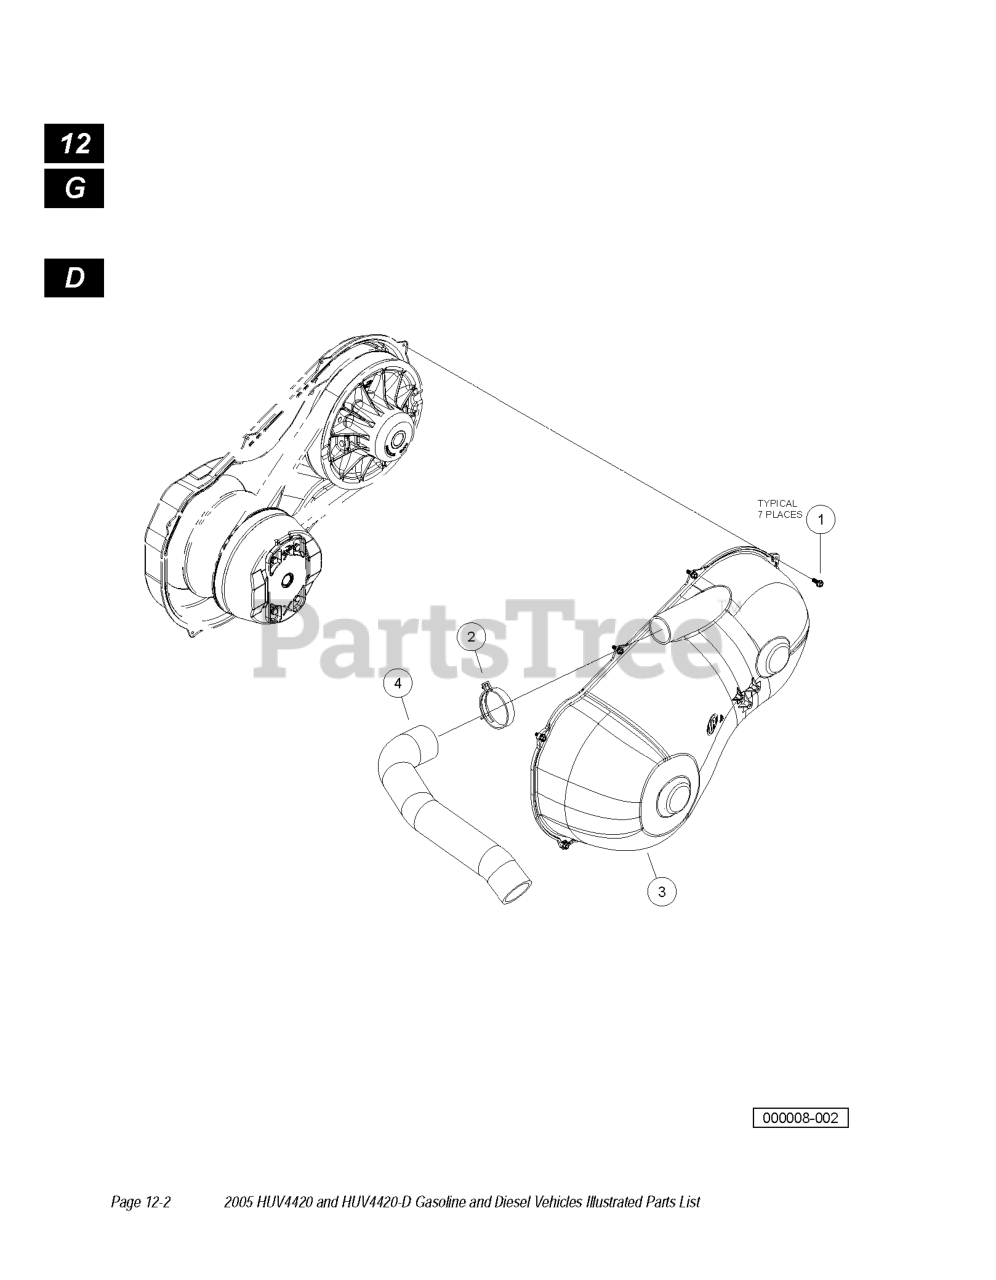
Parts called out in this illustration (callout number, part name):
1	SCREW, M6 X 16 TT HX FL HD
2	CLAMP, HOSE, CTB 64MM
3	COVER, CVT OUTER
4	HOSE, OUTLET, CVT
